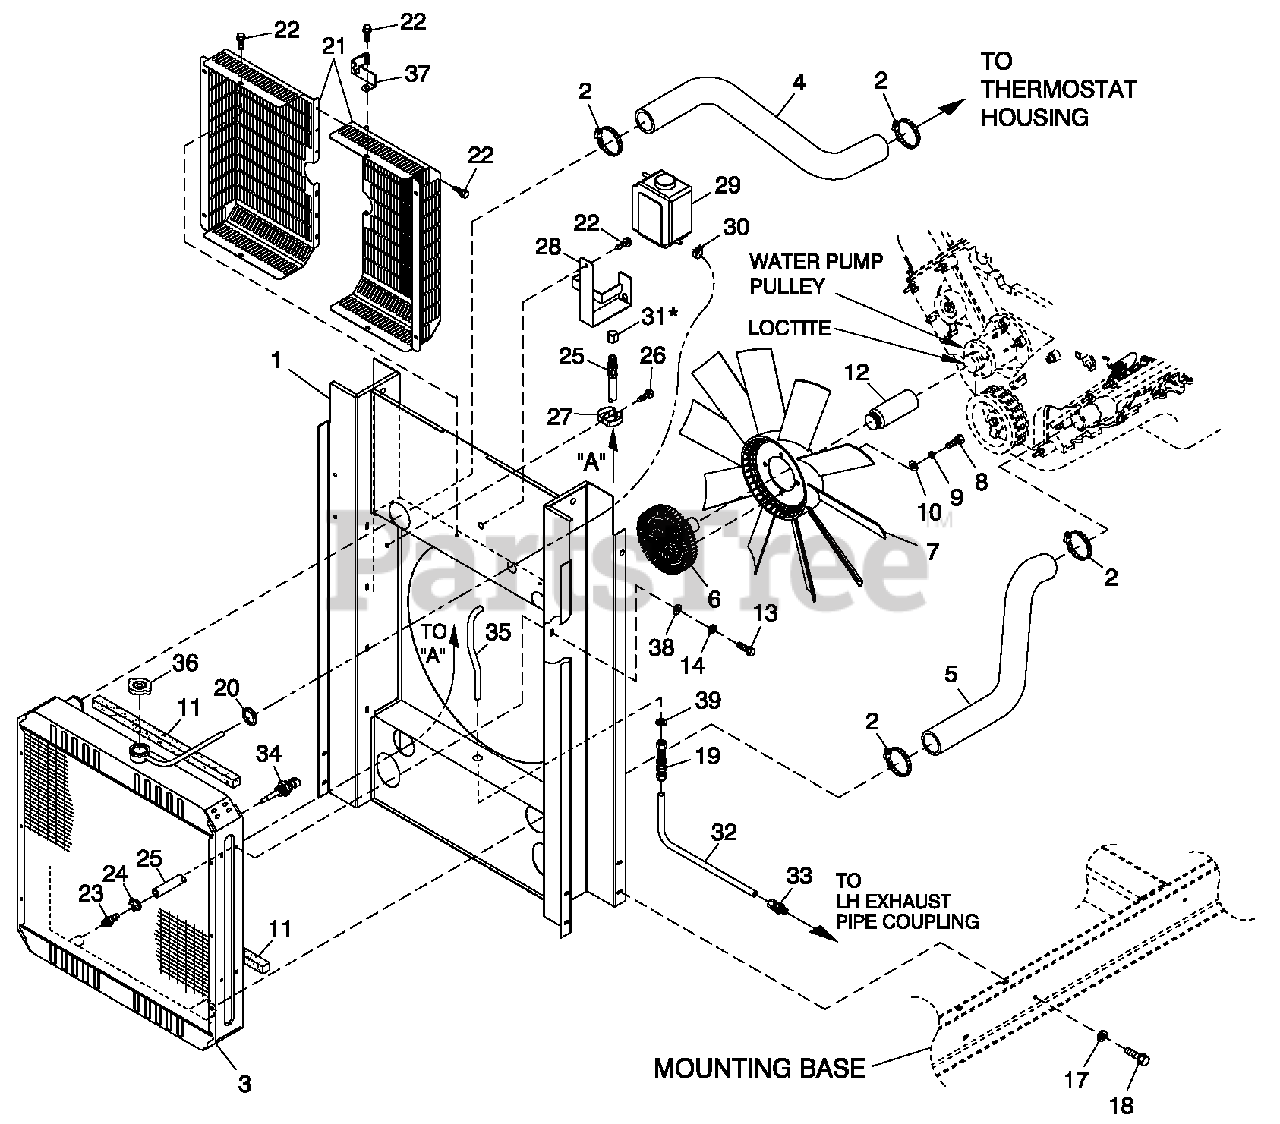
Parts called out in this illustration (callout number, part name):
1	WELDMENT RAD SUPPORT C3 (22")
2	CLAMP HOSE #28 1.32-2.25
3	RADIATOR 581 X 585 X 70 CPL LH
4	HOSE UPPER RADIATOR C3
5	HOSE LOWER RADIATOR C3
6	CLUTCH COOLING FAN
7	FAN 22" DIA 10 BLADE
8	SCREW HHC M10-1.5 X 20 G8.8
9	WASHER LOCK M10
10	WASHER FLAT 3/8-M10 ZINC
11	TAPE FOAM 1 X 1 (23" LG)
12	SPACER FAN 6.8L
13	SCREW HHC M8-1.25 X 20 G8.8
14	WASHER LOCK M8-5/16
17	WASHER LOCK M6-1/4
18	SCREW HHFC M6-1.0 X 20 G8.8
19	FTG CMPN BLKHD 3/8" OD TUBE BRS
20	GROMMET .75 X .12 X .50
21	GUARD FAN C3 CPL
22	SCREW THF M6-1 X 16 N WA Z/JS
23	BARBED STR 3/8 NPT X 3/8
24	CLAMP HOSE .38-.87
25	HOSE DRAIN ASSY 28"
26	SCREW HHTT M4-0.7 X 8 BP
27	SPRING CLIP HOLDER .37-.62
28	BRKT COOLANT RECOVERY TANK
29	TANK COOLANT RECOVERY
30	CLAMP HOSE BAND 1/4
31	CAP HEX 1/4 NPT BRASS
32	TUBE FAN CLUTCH PREHTR LOWR C3
33	FTG CMPR 3/8TUBE X 3/8 NPT W/FERL
34	PROBE COOLANT LEVEL 3/8 NPTF
35	TUBE FAN CLUTCH PREHTR UPPR C2
36	CAP RADIATOR 13 PSI
37	BRACKET SIGNAL CONDITIONER
38	WASHER FLAT 5/16-M8 ZINC
39	WASHER FLAT 9/16 ZINC
